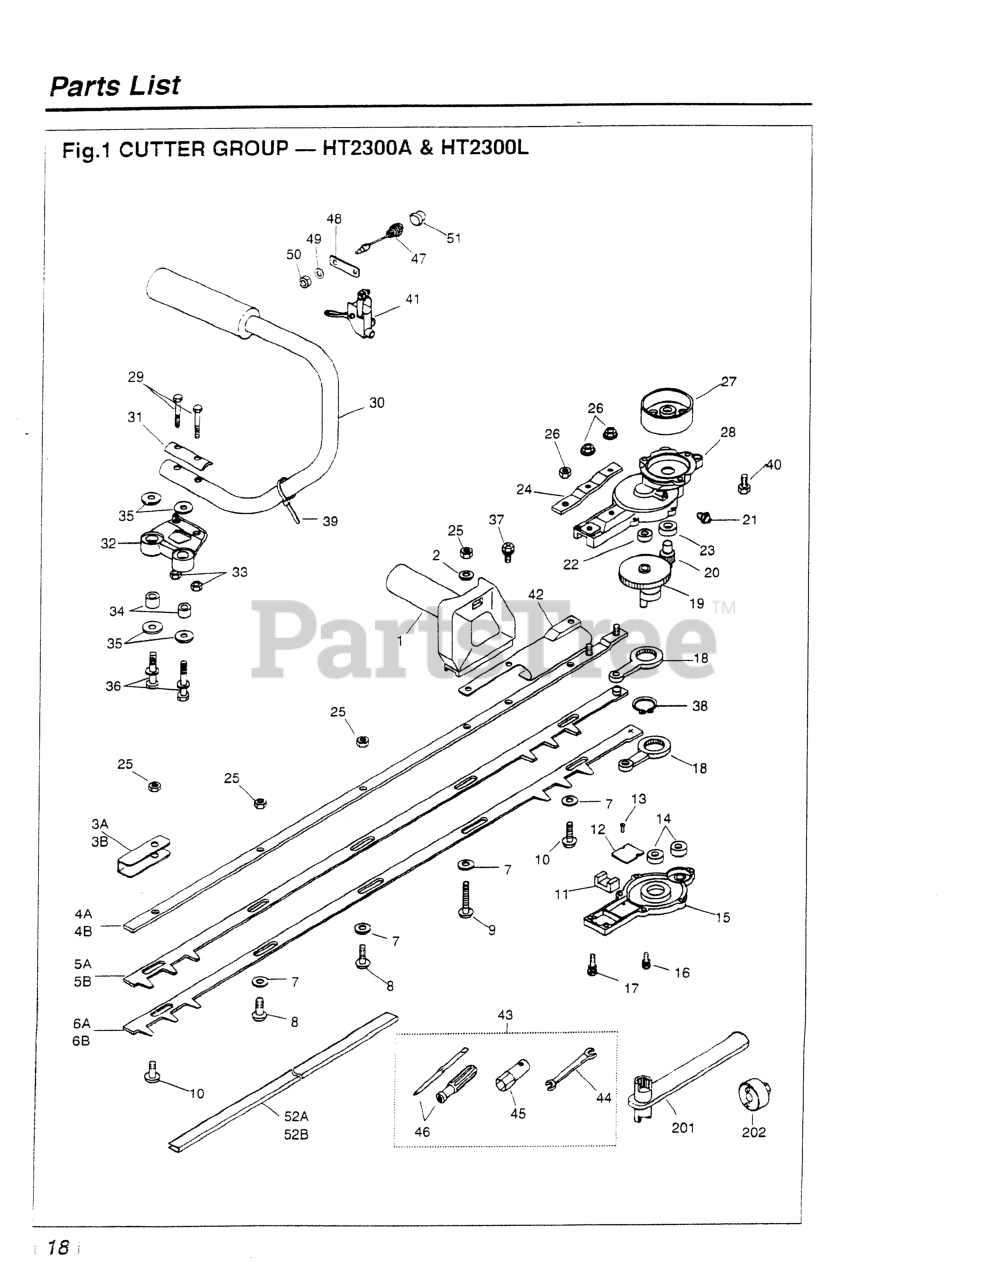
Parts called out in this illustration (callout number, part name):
1	HANDLE (RPLS -12100)
3B	REINFORCE
4B	GUIDE PLATE (RPLS -11611) 40
5B	BLADE, UPPER 40
6B	BLADE, LOWER 40
7	WASHER (RPLS 3873-11760)
11	FELT
12	PLATE
13	SCREW, M3 x 5
14	BEARING
15	CASE, LOWER
16	BOLT, M5 x 16
17	BOLT, M5 X 20
18	ROD
19	GEAR COMPLETE
20	PINION
21	FITTING, GREASE
22	BEARING
23	BEARING
24	PLATE (RPLS 3880-11130)
25	NUT, M6
26	NUT
27	DRUM, CLUTCH
28	CASE, UPPER (RPLS -11110)
29	BOLT, M5X30 (RPLS -50350)
30	HANDLE, LEFT
32	BRACKET
33	NUT (RPLS 3873-14470)
37	BOLT
38	RING, SNAP, M25 X 1.2
39	BAND, CABLE
40	BOLT, M6 X 14
41	LEVER ASSEMBLY
42	PROTECTOR
43	TOOL SET
44	SPANNER, 8 X 10 (RPLS 2540- )
45	SOCKET, HEX, 3/4
46	SCREWDRIVER
48	PLATE
49	WASHER
50	NUT
51	CAP
52B	COVER, BLADE (40
202	WRENCH (TOOL)
